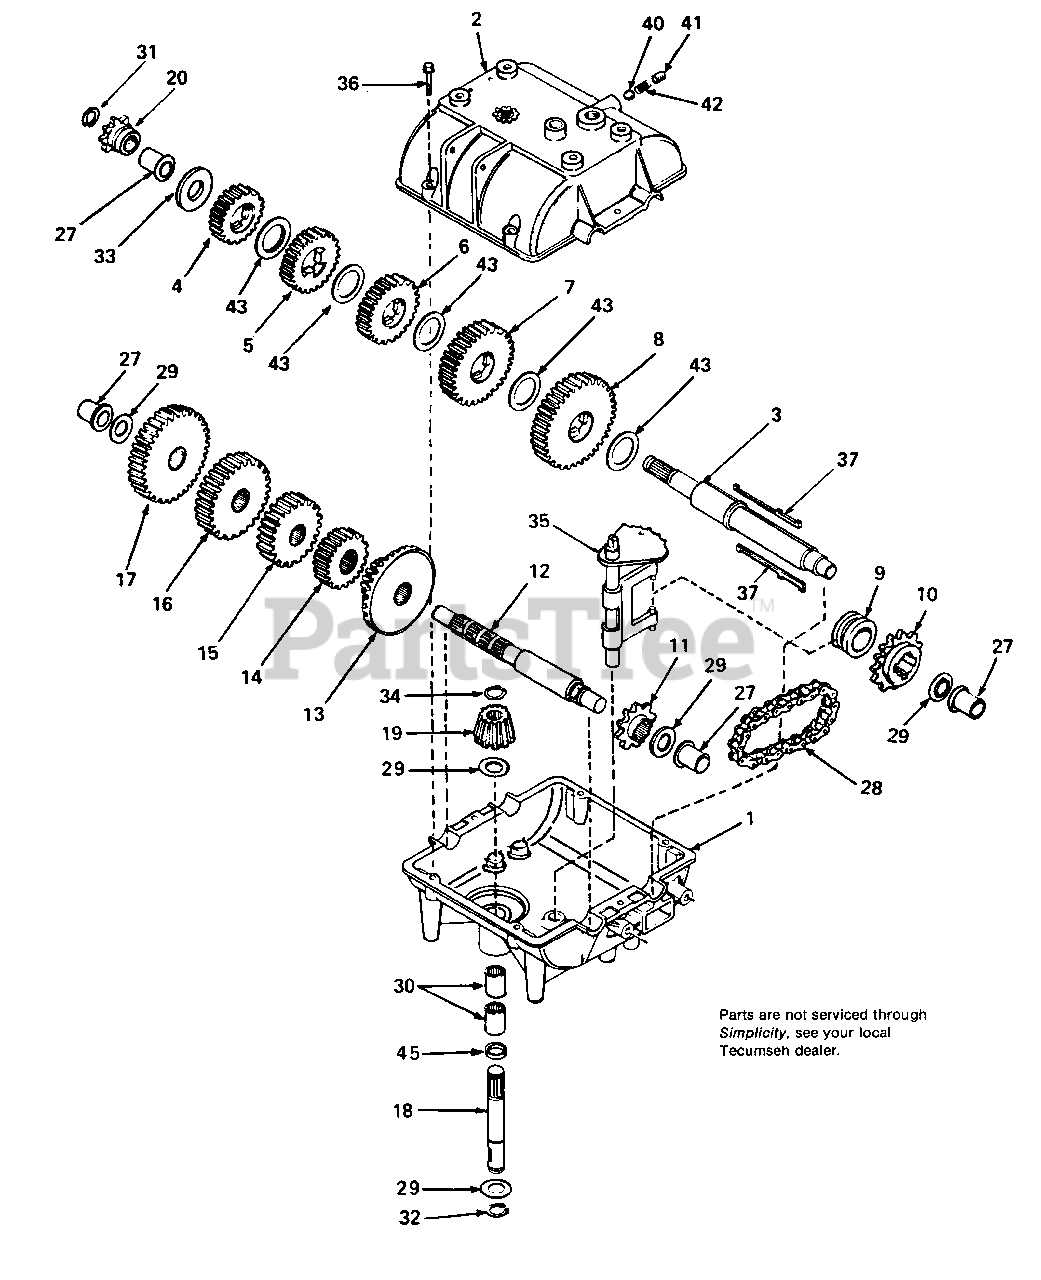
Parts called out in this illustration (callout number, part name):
1	CASE, Transmission
2	COVER, Transmission
3	SHAFT, Output
4	GEAR, Spur (20 teeth)
5	GEAR, Spur (22 teeth)
6	GEAR, Spur (25 teeth)
7	GEAR, Spur (30 teeth)
8	GEAR, Spur (35 teeth)
9	COLLAR, Shift
10	SPROCKET (18 teeth)
11	SPROCKET (9 teeth)
12	SHAFT, Counter
13	GEAR, Bevel (42 teeth & 15 tooth spur gear)
14	GEAR, Spur (20 teeth)
15	GEAR, Spur (25 teeth)
16	GEAR, Spur (28 teeth)
17	GEAR, Spur (30 teeth)
18	SHAFT, Input
19	BEVEL PINION, Input
20	SPROCKET (8 teeth)
27	BUSHING, Flanged
28	CHAIN, Roller (No. 41 chain, 24 links)
29	RACE, Thrust
30	BEARING, Needle
31	RING, Retaining
32	RING, Retaining
34	RING, Retaining
35	ROD & FORK ASSY., Shift
36	SCREW, Hex Hd., Taptite, 1/4-20 x 1-1/4
40	BALL, Steel, 5/16
41	SCREW, Set, 3/8-16 x 3/8
43	WASHER, Thrust
45	RING, Square Cut
